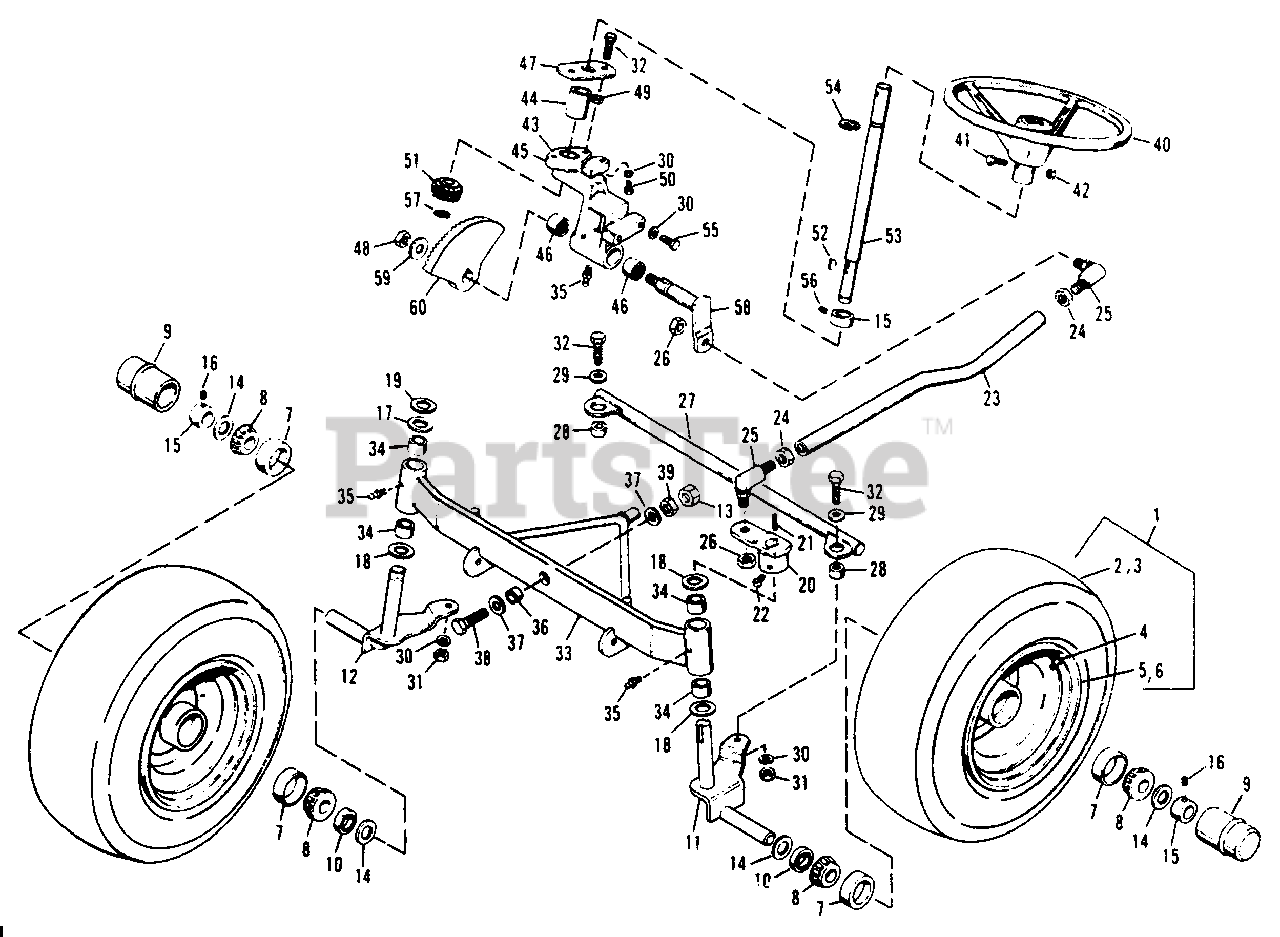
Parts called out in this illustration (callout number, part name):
1	Wheel & Tire Assembly
4	Valve Stem & Cap
5	Wheel-Sub Assembly
6	Wheel (Front)
7	Bearing, Cup
8	Bearing, Cone (Without Seal)
9	Hub Cap
11	Spindle Assy., L.H.
12	Spindle Assy., R.H.
13	Hex Jam Nut, 1/2"-13
15	Collar, Set
16	Set Screw,5/16"-18 x 5/16"
17	Washer (Use Beneath Snap Ring)
19	Ring, Retaining
20	Arm Assy., Strg. L.H.
22	Set Screw, 5/16"-18 x 1/2"
24	Hex Jam Nut, 1/2"-20 N.F.
25	Joint, Ball
26	Hex Nut, Jam Lock, 1/2"-20
27	Link Assy., Drag
29	Washer, Plain, 3/8"
30	Lockwasher, 3/8"
31	Full Hex Nut, 3/8"-16 N.C.
32	Hex Capscrew, 3/8"-16 x 1-1/4"
33	Axle Assy., Front
35	Fitting, Grease
37	Plain Washer, 1/2"
38	Hex Capscrew
39	Nut, Toplo, 1/2"-13
40	Steering Wheel
41	Hex Capscrew, 5/16"-18 x 1-1/4"
42	Hex Lock Nut, 5/16"-18 N.C.
43	Steering Bracket, Casting
44	Bushing, Steering
45	Casting and Bearing
46	Bearing, Needle
47	Plate, Steering
48	Hex Lock Nut, 7/16"-14 N.C.
49	Hex Jam Nut, 3/8"-16
50	Hex Capscrew, 3/8"-16 x 3/4"
51	Pinion, 15T, Bevel
52	Key, Woodruff
53	Shaft, Steering
54	Ring, Retaining
55	FIex Capscrew, 3/8"-16 x 7/8"
56	Set Screw, 5/16"-18 N.C. x 1/4"
57	"E" Ring
58	Arm Assy. Steering
59	Plain Washer, 7/16"
60	Gear, 23 T, Bevel
